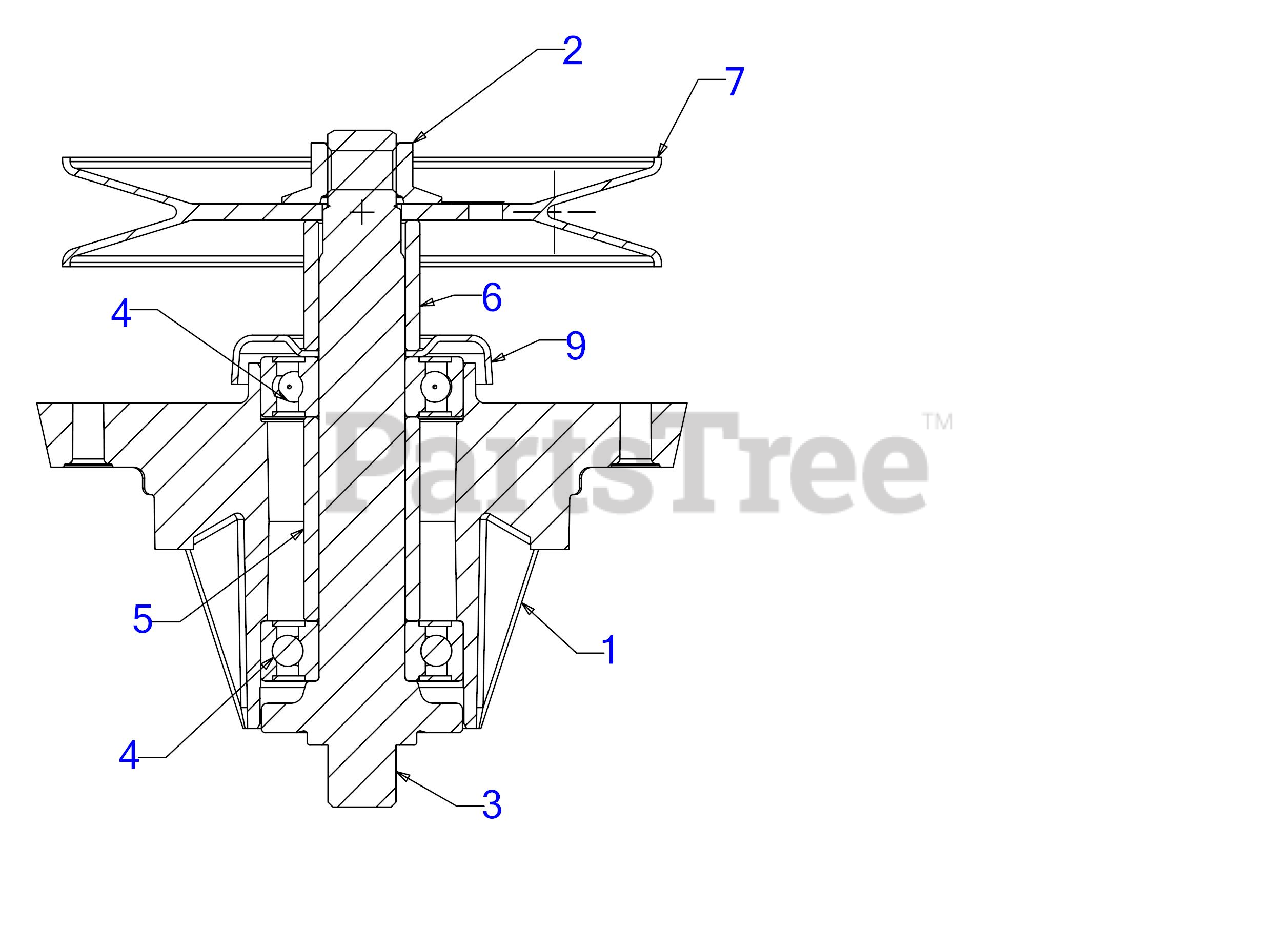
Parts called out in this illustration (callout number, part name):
1	DECK SPINDLE HOUSING
2	FLANGE NUT 5/8-18
3	BLADE SPINDLE SHAFT
4	BALL BEARING
5	SPACER- .792 x 1.060 x 1.860
6	SPACER .792 x 1.060 x 1.191
7	SPINDLE PULLEY 5.57" DIA
9	SHIELD-BRG DECK
